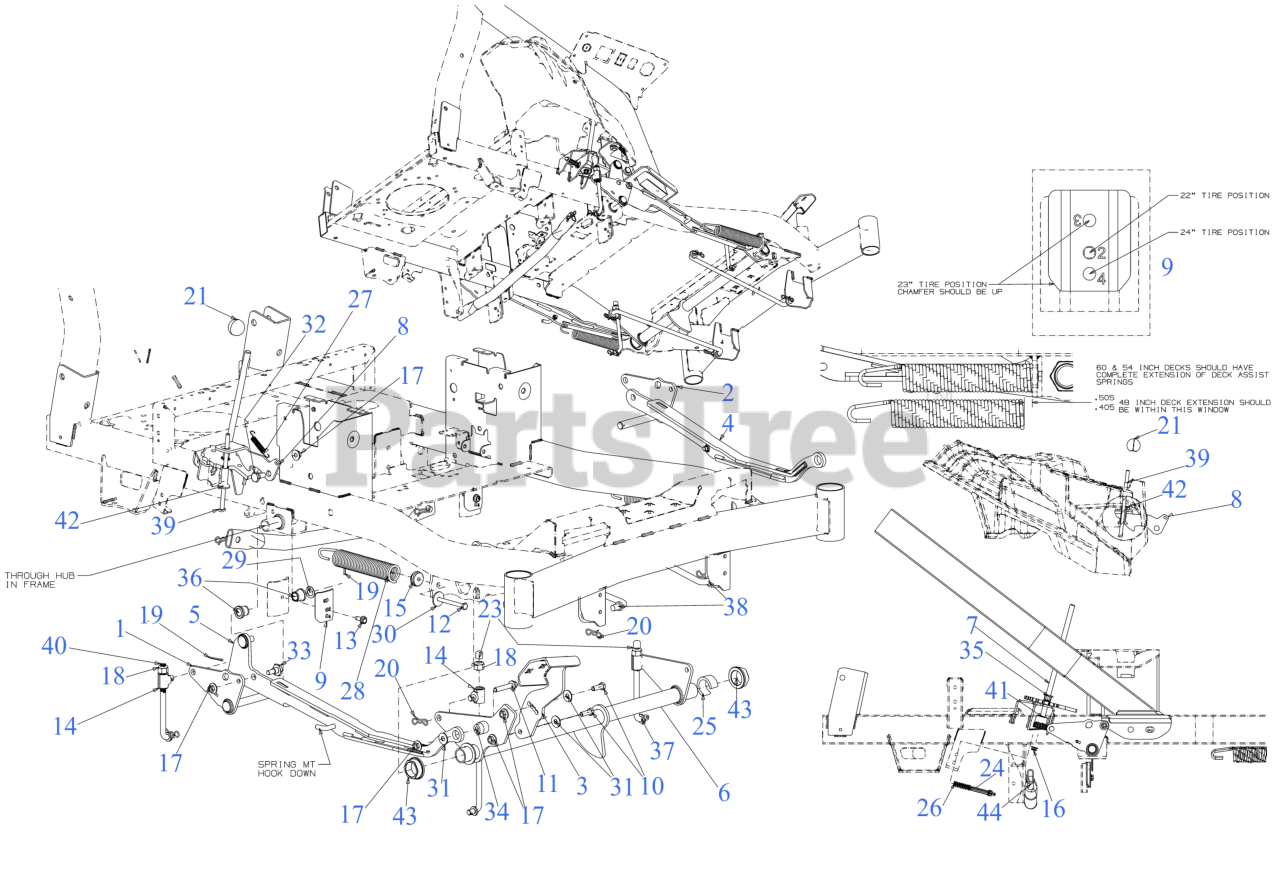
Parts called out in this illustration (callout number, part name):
1	BELLCRANK BRACKET (RH)
2	BELLCRANK BRACKET (LH)
3	DECK LIFT PEDAL
4	LIFT LINK (LH)
5	LIFT LINK (RH)
6	LIFT TUBE (FRONT)
7	DECK HEIGHT ADJUSTMENT ROD
8	TRAVEL LOCK PLATE
9	UPSTOP BRACKET
10	SCREW 3/8-16 x 1 GR5
11	SCREW 3/8-16 x 2.00 GR5
12	SCREW 5/16-18 x 3.50 GR5
13	SCREW 5/16-18 x .750
14	LIFT ROD FERRULE
15	LIFT SPRING INSERT
16	FLANGE LOCK NUT 5/16-18
17	FLANGE LOCK NUT
18	HEX LOCK NUT NYLON
19	COTTER PIN
20	BOW TIE COTTER PIN
21	BALL KNOB
23	LIFT ROD END CAP
24	DETENT PLUNGER
25	LIFT TUBE SPACER
26	COMPRESSION SPRING .531 OD 1.75 LG
27	EXTENSION SPRING 2.675"
28	EXTENSION SPRING
29	FLAT WASHER
30	WASHER-5/16 x 1.25X 1.27
31	WASHER-.395 x 1.0 x .62
32	SHOULDER SCREW
33	SHOULDER SCREW .50 x .385
34	SHOLUDER SPACER
34	HEX FLANGE BEARING .506ID x .590LG
36	FLANGE BUSHING
37	DECK LIFT ROD 6.875"
38	DECK CONTROL ROD
39	TRAVEL LOCK ROD
40	DECK LIFT ROD 6.562"
41	DECK HEIGHT DETENT HUB
42	LOCK ROD SLEEVE SPACER
43	FLANGE BEARING
44	DECK STABILIZER TUBE
